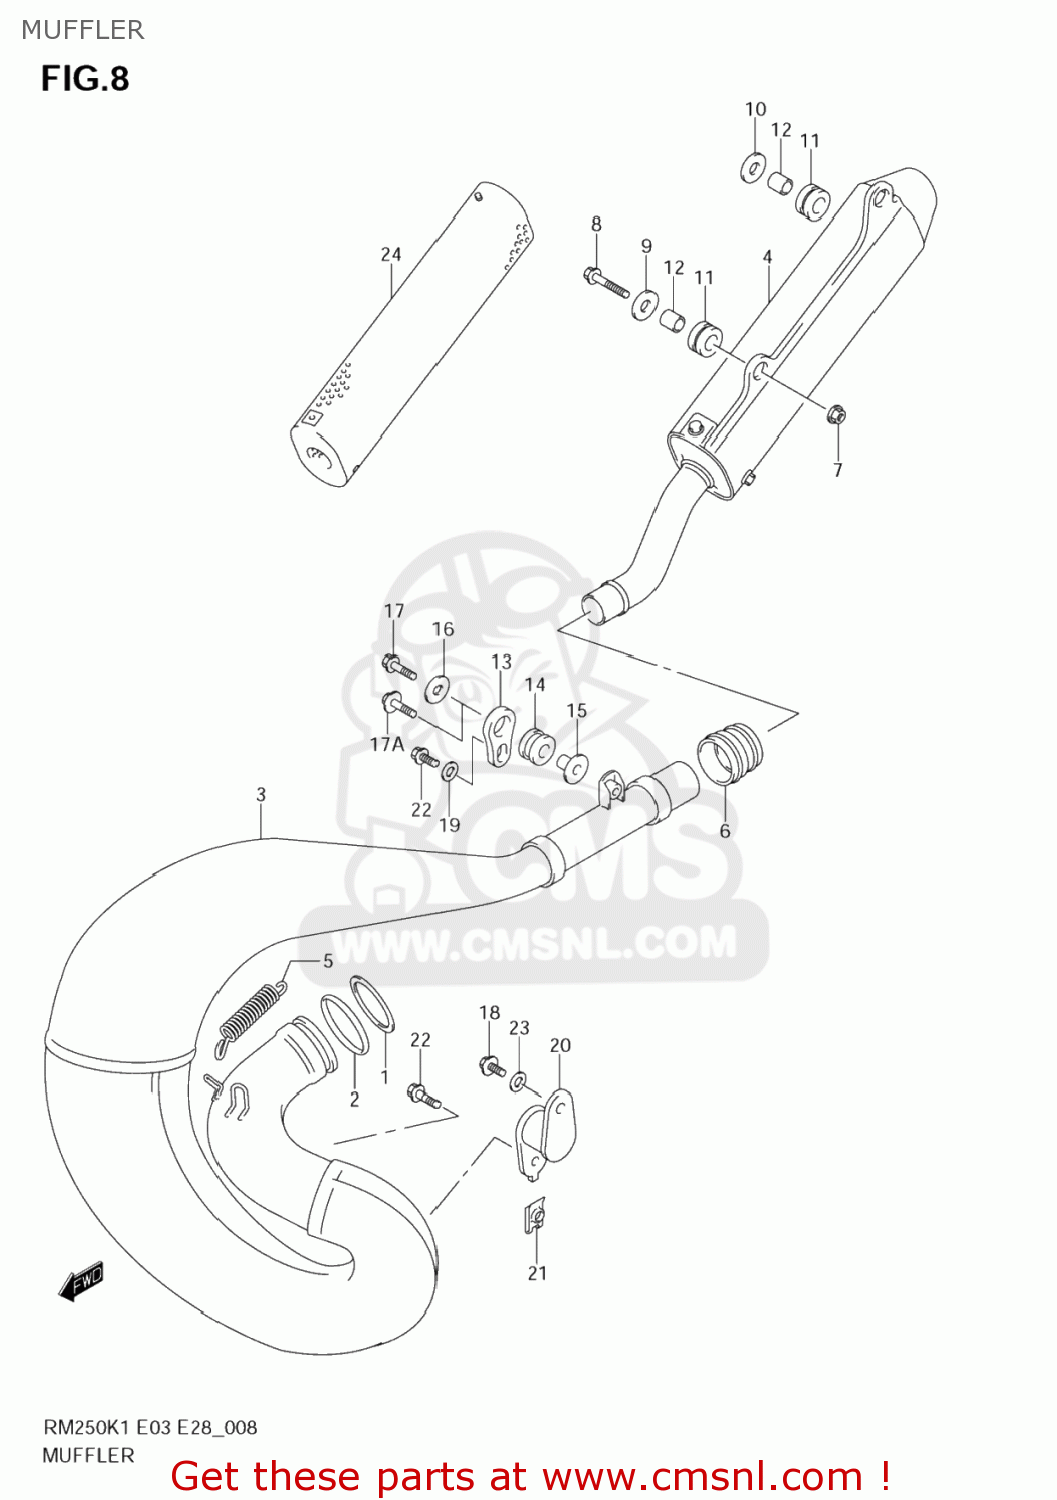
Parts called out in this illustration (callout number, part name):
1	WASHER,EXHAUST PIPE
2	O RING,EXHAUST PIPE
3	BODY,MUFFLER
4	BODY,MUFFLER 2ND
5	SPRING
6	CONNECTOR,MUFFLER
7	NUT
8	BOLT(6X30)
9	WASHER(6.5X24X1.2)
10	WASHER(6.5X24X1.2)
11	CUSHION
12	SPACER(6.5X11.5X12)
13	PLATE,MUFFLER MTG
14	CUSHION,MUFFLER
15	SPACER,MUF MTG
16	WASHER(6.5X24X1.2)
17	SCREW
17A	BOLT(6X25)
18	BOLT
19	WASHER(6.5X18X1.6)
20	DAMPER,MUFFLER
21	HOLDER,REAR BU
22	BOLT
23	WASHER(6.5X18X1.6)
24	SILENCER,MUFFLER
